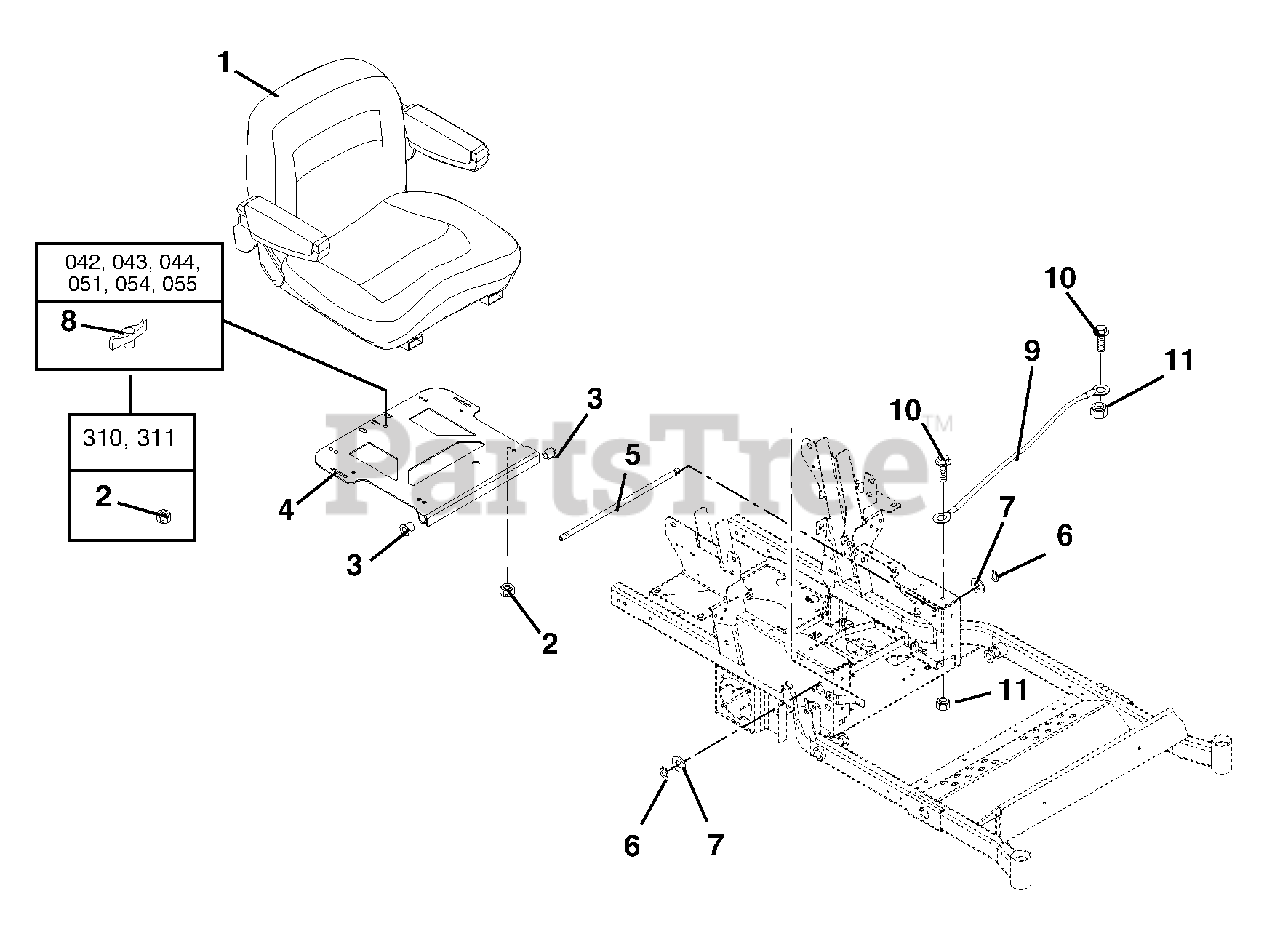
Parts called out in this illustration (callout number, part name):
2	Nut, Locking Top Flange .31-18 (042, 043, 044, 051, 054, 055)
2	Nut, Locking Top Flange .31-18 (310, 311)
3	Bushing, Flange .515 x .750 x .745 x 1.00
4	Seat Pivot Mount
5	Rod, Seat Frame Pivot
6	Ring, Retaining External .500 x .050
7	Washer, Flat Steel .531 x 1.06 x .095
8	Knob, Wing .312-18 (042, 043, 044, 051, 054, 055)
9	Cable, Hood
10	Bolt, Hex .25-20 x .75 Grade 5
11	Nut, Locking Top Flange .25-20
